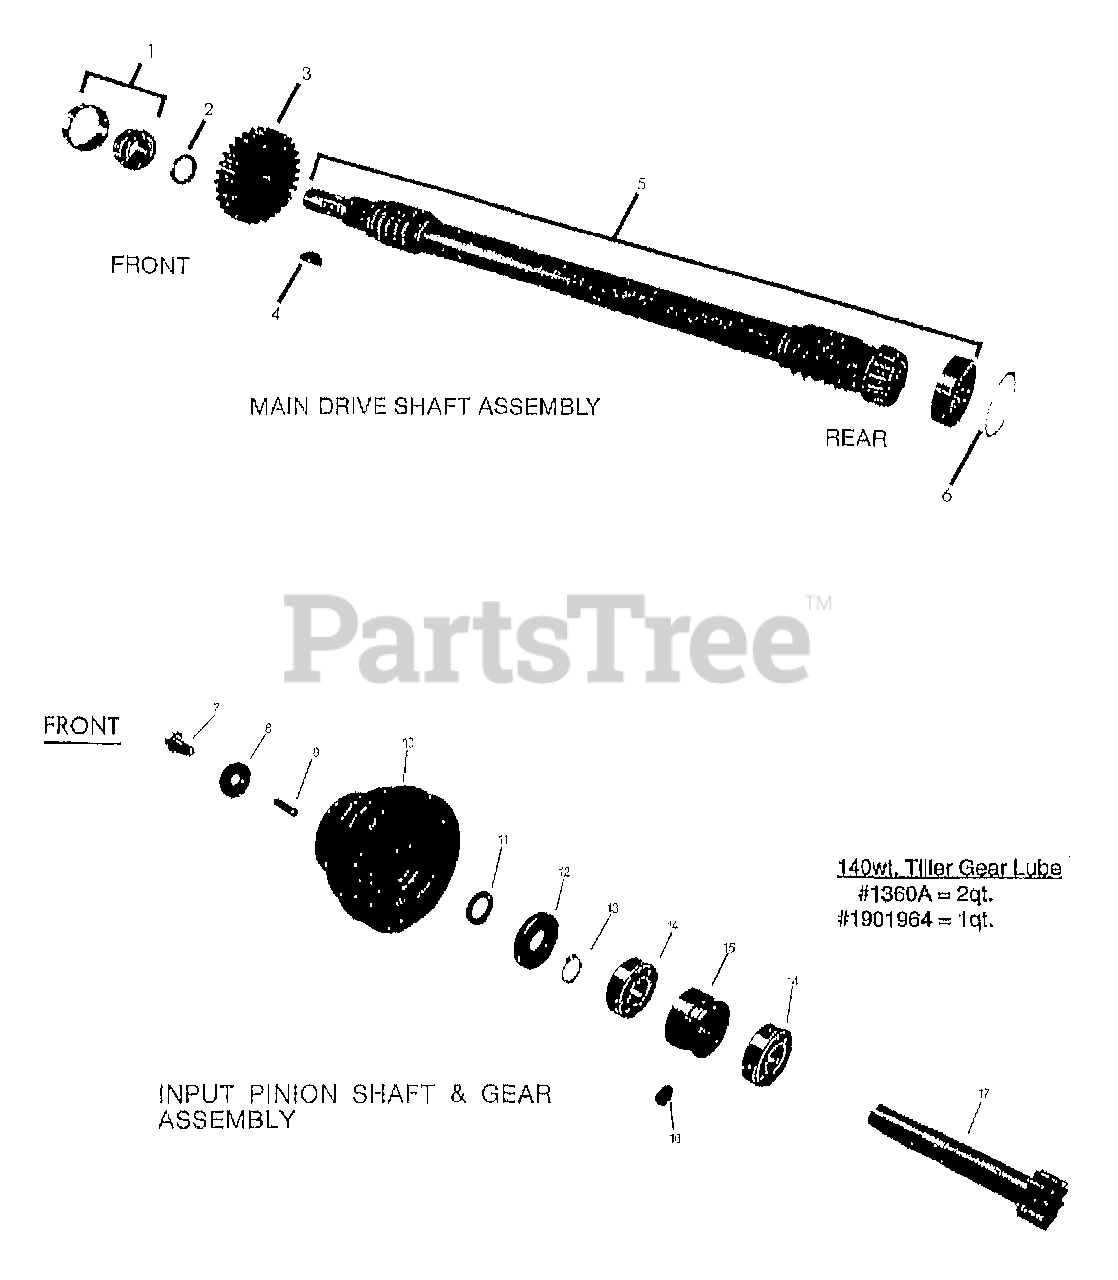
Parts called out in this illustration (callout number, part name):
1	KIT-BRG CONE&RACE-DRIVESHAFT
2	WASHER-# 1.125X.75X.047
3	GEAR-SPUR 30 TEETH
4	KEY-WOODRUFF #607
5	KIT-DRIVESHAFT PONY 1 (RACE INCL.)
6	SHIM-1.75X1.5X.01
6	SHIM-1.75X1.5X.03
6	SHIM-1.75X1.5X.005
7	SCR-HH 5/16-24X.75 G5 ZP
8	WASHER-.827X.331X.098
9	KEY-.188 SQX1.0
10	PULLEY-TRANS MACH (3 GROOVES)
11	WASHER-1.03X.614X.075
12	SEAL-OIL PINION SHAFT
13	RING-RETAIN EXT .669 ID (SNAP RING)
14	BRG-METRIC
15	SPACER-1.57X1.25X.927
16	SCR-SS 5/16-18 X .5
17	GEAR-SPLINE 10 TEETH POL (HARDENED TEETH)
